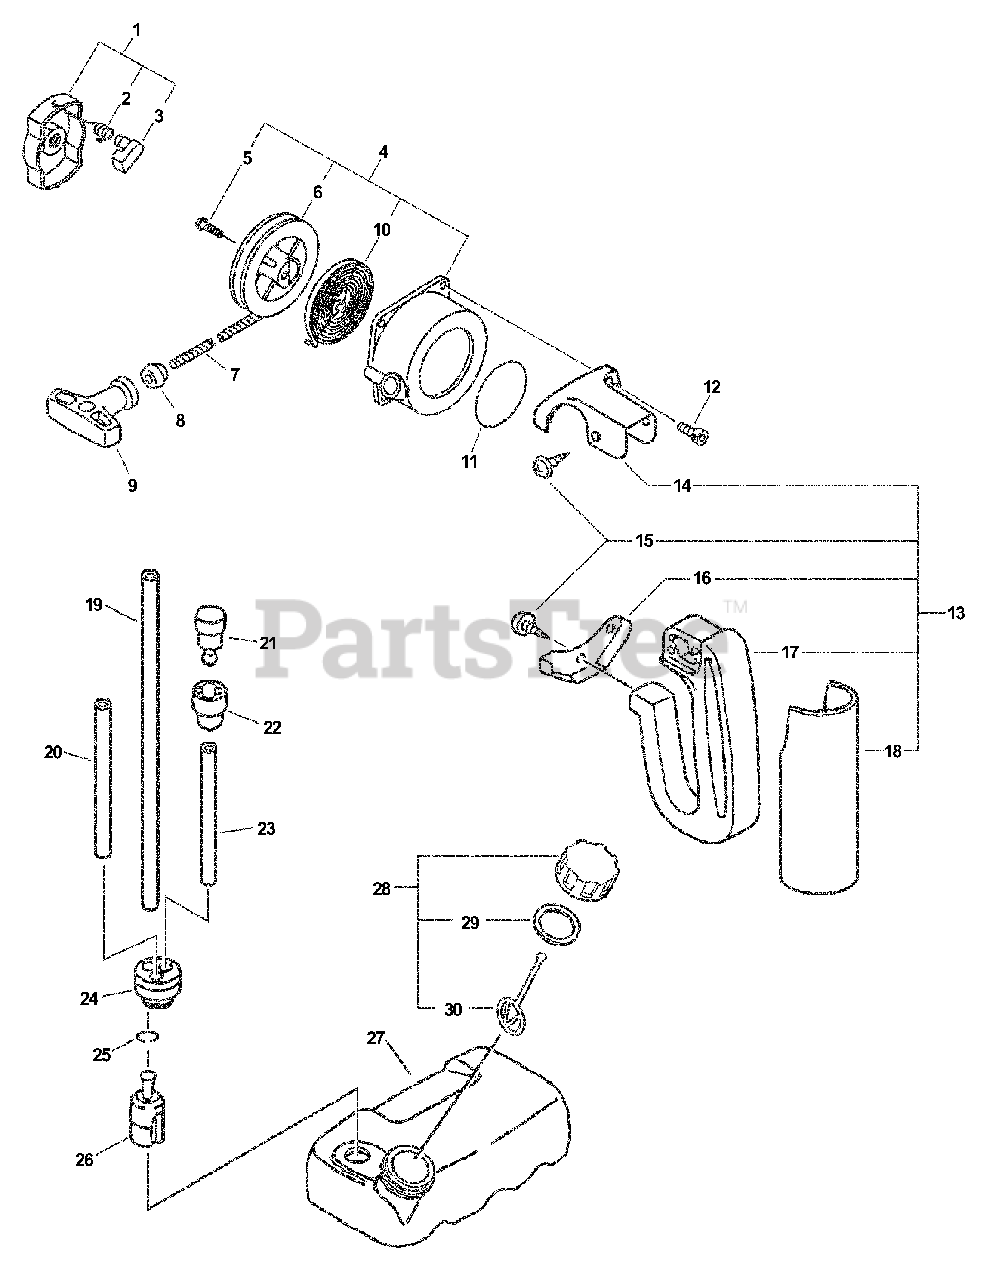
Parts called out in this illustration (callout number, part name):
1	PAWL ASSY, STARTER
2	SPRING, RETURN
3	PAWL, STARTER - BLACK
4	STARTER ASSY
5	SCREW
6	REEL, ROPE
7	ROPE, STARTER
8	GUIDE, ROPE
9	GRIP, STARTER
10	SPRING, RECOIL
11	LABEL, ECHO
12	BOLT 4×18
13	SIDE HANDLE ASSY
14	BRACKET, HANDLE
15	SCREW 5×16
16	BRACKET, HANDLE
18	GRIP, HANDLE
19	PIPE, FUEL 3×6×200
20	PIPE, FUEL 3×6×100
21	VENT ASSY
22	HOLDER, VENT
23	PIPE, FUEL 3×6×100
24	GROMMET, FUEL
25	CLIP Ø6.5 MM
26	FILTER, FUEL
27	TANK, FUEL
28	CAP ASSY, FUEL
29	GASKET, FUEL CAP
30	CONNECTOR, CAP L= 100 MM
